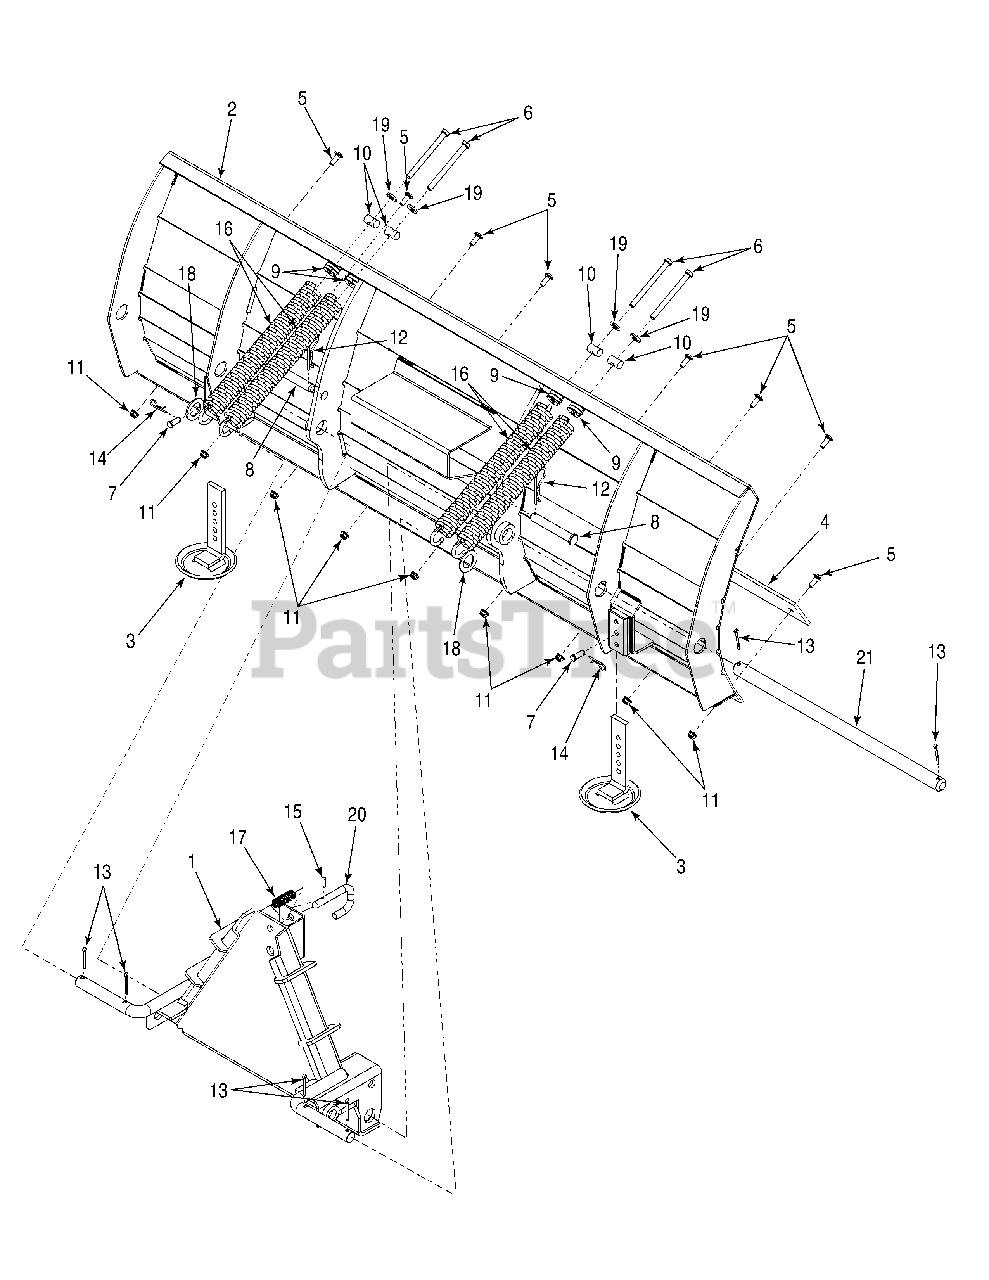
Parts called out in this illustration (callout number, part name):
1	Frame, Blade Mounting
2	Blade Assembly
4	Blade, Scraper
5	Bolt, Carriage, 5/16-18 x .875
6	Screw, Hex Cap, 3/8-16 x 4.25 Gr5
7	Pin, Clevis, .375 x .969
8	Pin, Clevis, .625 x 4.25
9	Insert, Spring
10	Roller, Spring
11	Nut, Hx insert Flange Lock, 5/16-18 GrF
12	Pin, Internal Cotter
13	Pin, Cotter, 3/16 x 1.5
14	Pin, Internal Cotter
15	Pin, Spirol, 3/16 x 3/4
16	Spring, Adjustment
17	Spring, Compression, .57 x 2.09
18	Washer, Flat, 1.0 x 1.75 x .107
19	Washer, Flat, .406 x .875 x .105
20	Pin, Front Hitch
21	Rod, Blade Pivot
